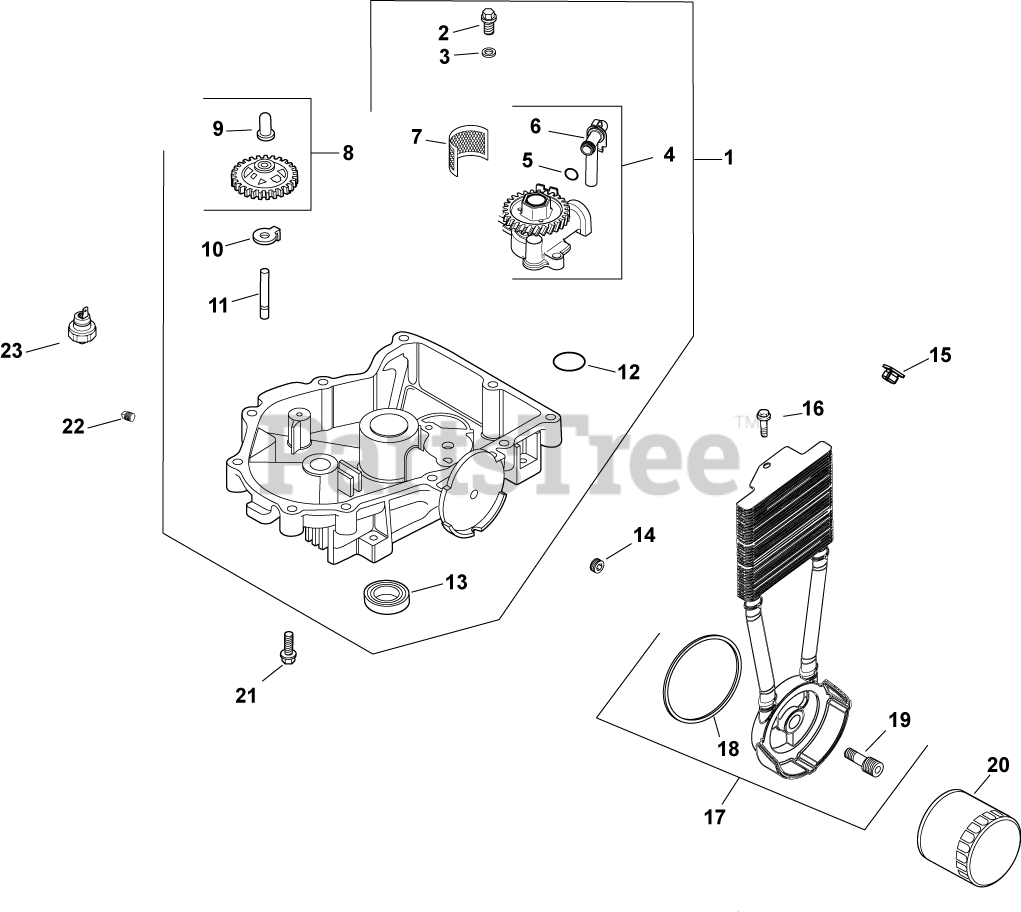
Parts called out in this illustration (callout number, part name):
1	PAN , OIL ASSEMBLY USE 24 199 32-S
2	SCREW,FLG THD FRM M6X1.0X25-(#25086395S)
3	WASHER, FLAT 6 MM
4	PUMP ASSEMBLY, OIL-USE 24 393 53-S
5	O-RING, OIL PICK-UP
6	KIT, OIL PICK-UP TUBE
7	SCREEN, OIL
8	KIT, GOVERNOR GEAR W/PIN
9	PIN, GOVERNOR REGULATING
10	TAB, LOCKING
11	SHAFT, GOVERNOR GEAR
13	SEAL, OIL
14	PLUG, PIPE CTSK 3/8"
15	NUT, PLASTIC (KM)-USE 25 100 37-S
16	SCREW, TAP M6X1.7X18
17	KIT, OIL COOLER
18	O-RING, OIL COOLER
19	NIPPLE, OIL FILTER
20	OIL FILTER
21	SCREW, FLG M8X1.25X45
22	PLUG, HD PIPE 3/8"
23	SENSOR, OIL PSI
